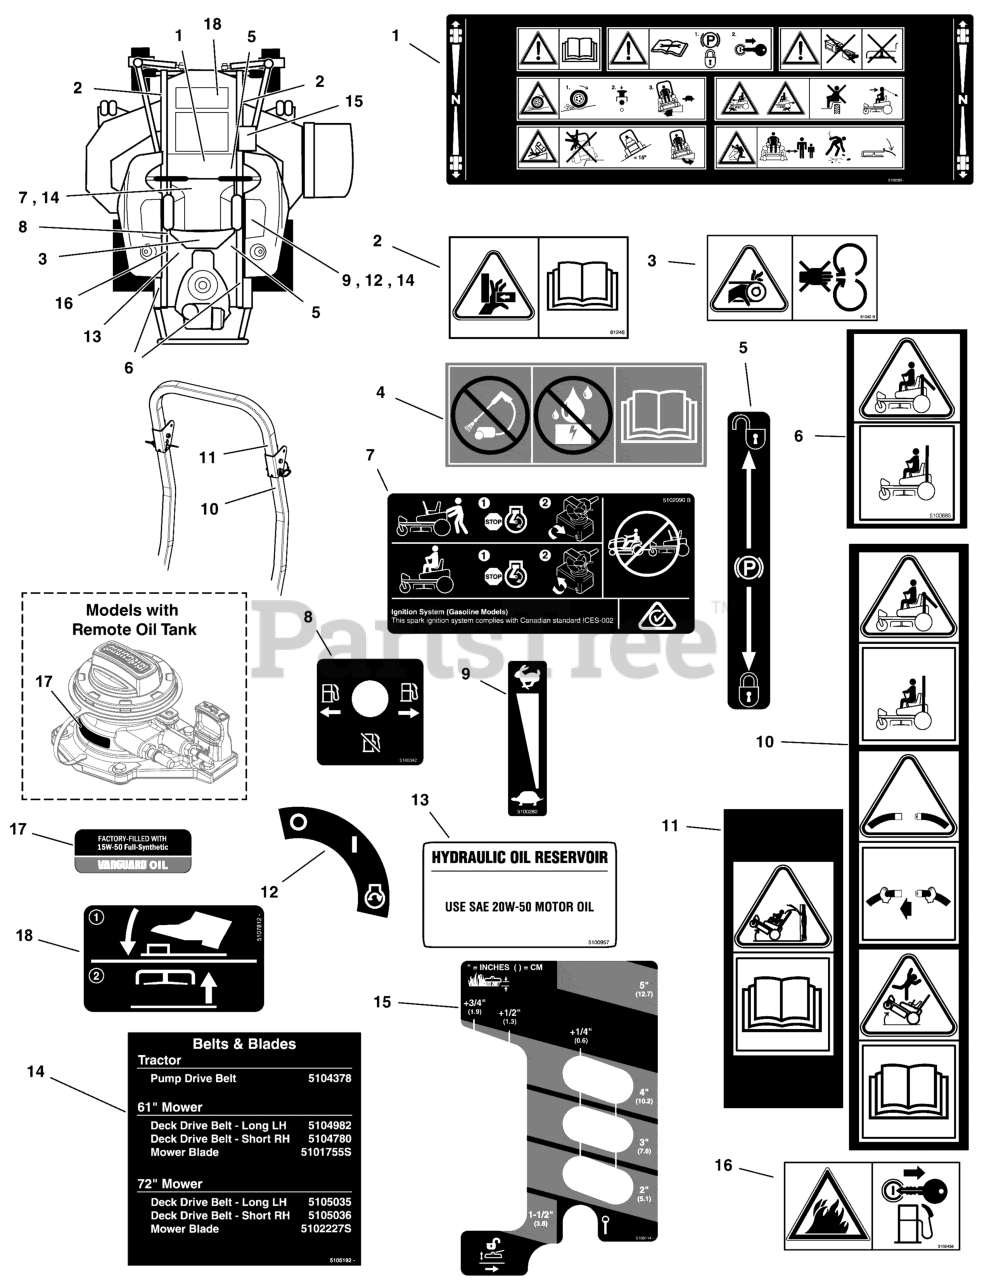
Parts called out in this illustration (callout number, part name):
1	DECAL, MAIN SAFETY, EXPORT
2	DECAL, Pinch Point, CE
3	DECAL, CE DANGER, HAND IN BELT
4	DECAL, DO NOT PRESSURE WASH
5	DECAL, PARKING BRAKE SYMBOLS
6	DECAL, WARNING, ROLL BAE, CE
7	DECAL, TRANSAXLE RELEASE, S200XT
8	DECAL, FUEL VALVE
9	DECAL, Throttle Control
10	DECAL, SAFETY, CE ROPS (SV)
11	DECAL, SAFETY, CE ROPS, OBS (SV)
12	DECAL, IGNITION CONTROL
13	DECAL, HYDRAULIC OIL, SAE 20W50
14	DECAL, BELT & BLADE IS3200Z 2BELT
15	DECAL, CUTTING HEIGHT
16	DECAL, FIRE ANSI EXPORT
17	LABEL, OIL INFORMATION
18	DECAL, FOOT OPERATED DECK LIFT
